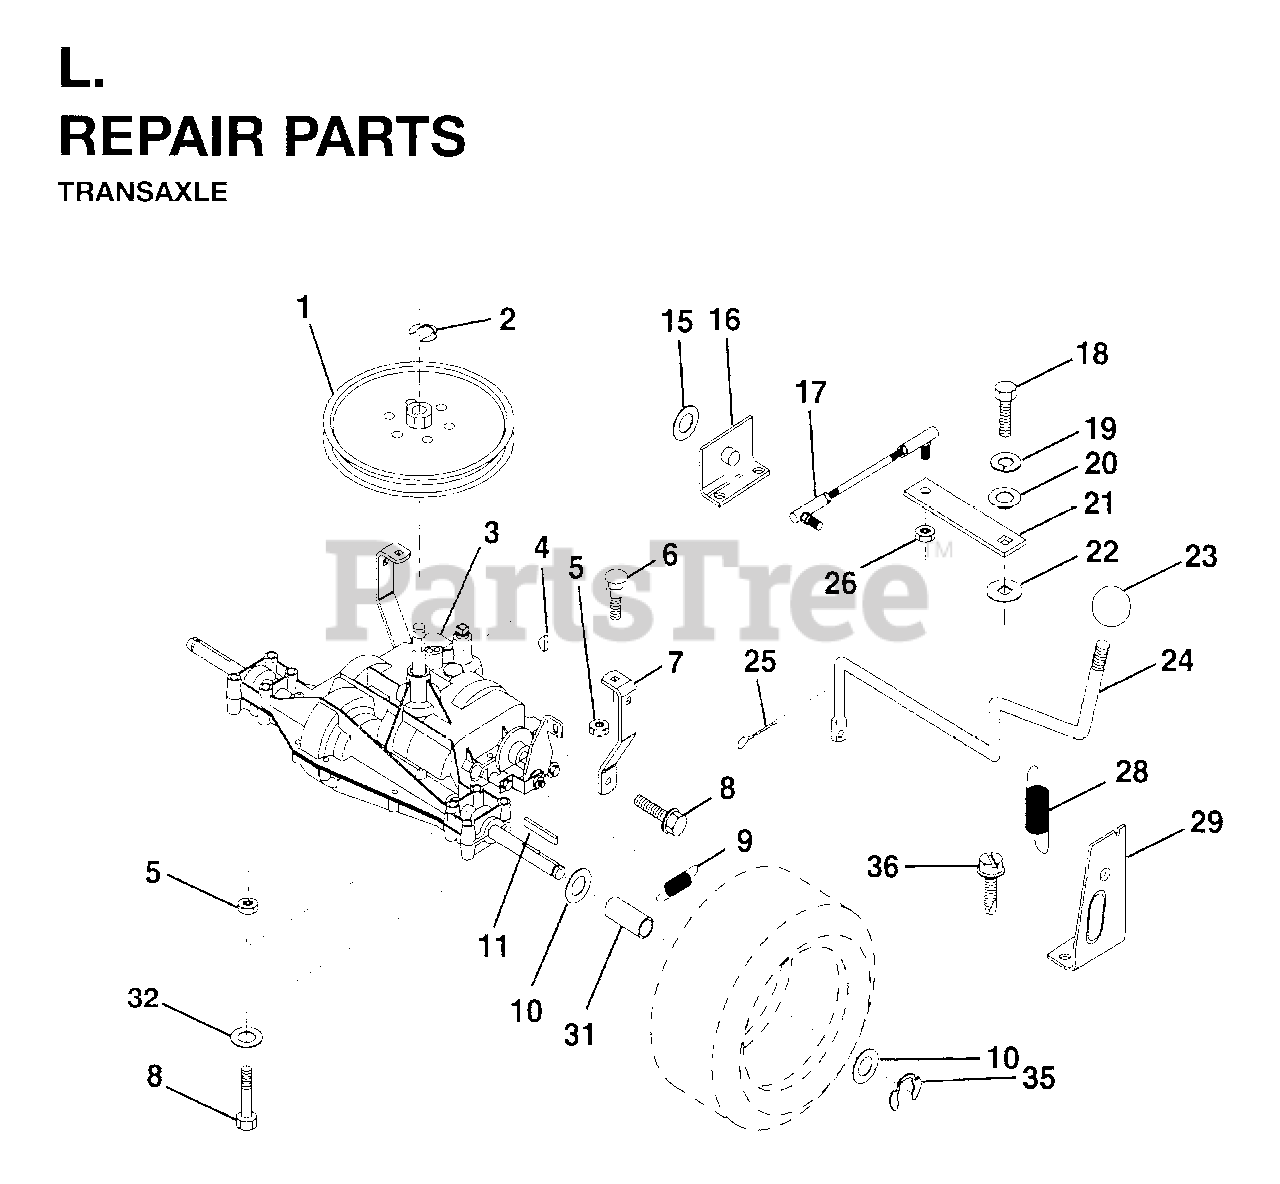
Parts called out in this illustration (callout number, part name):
2	RETAINING RING
5	NUT.71038.31-18.HEX.NYLOCK
6	BOLT
7	STRAP,TORQUE
8	BOLT
9	SPRING,BRAKE RETURN
11	SQUARE KEY
15	WASHER - M12
16	SUPT, HDLE SHT LH
18	BOLT 1/4-28X3/4
19	LOCKWASHER
20	WASHER - 26X6.5X1.6
22	WASH-SHFT PLT LT
23	KNOB.DUCKHEAD.1/2
24	ROD, SHIFT
25	PIN COTTER
28	SPRING.EXTENSION
29	SUPPORT HANDLE SHAFT RH
31	SPACER AXLE
32	WASHER
35	E-RING LT
36	BOLT
